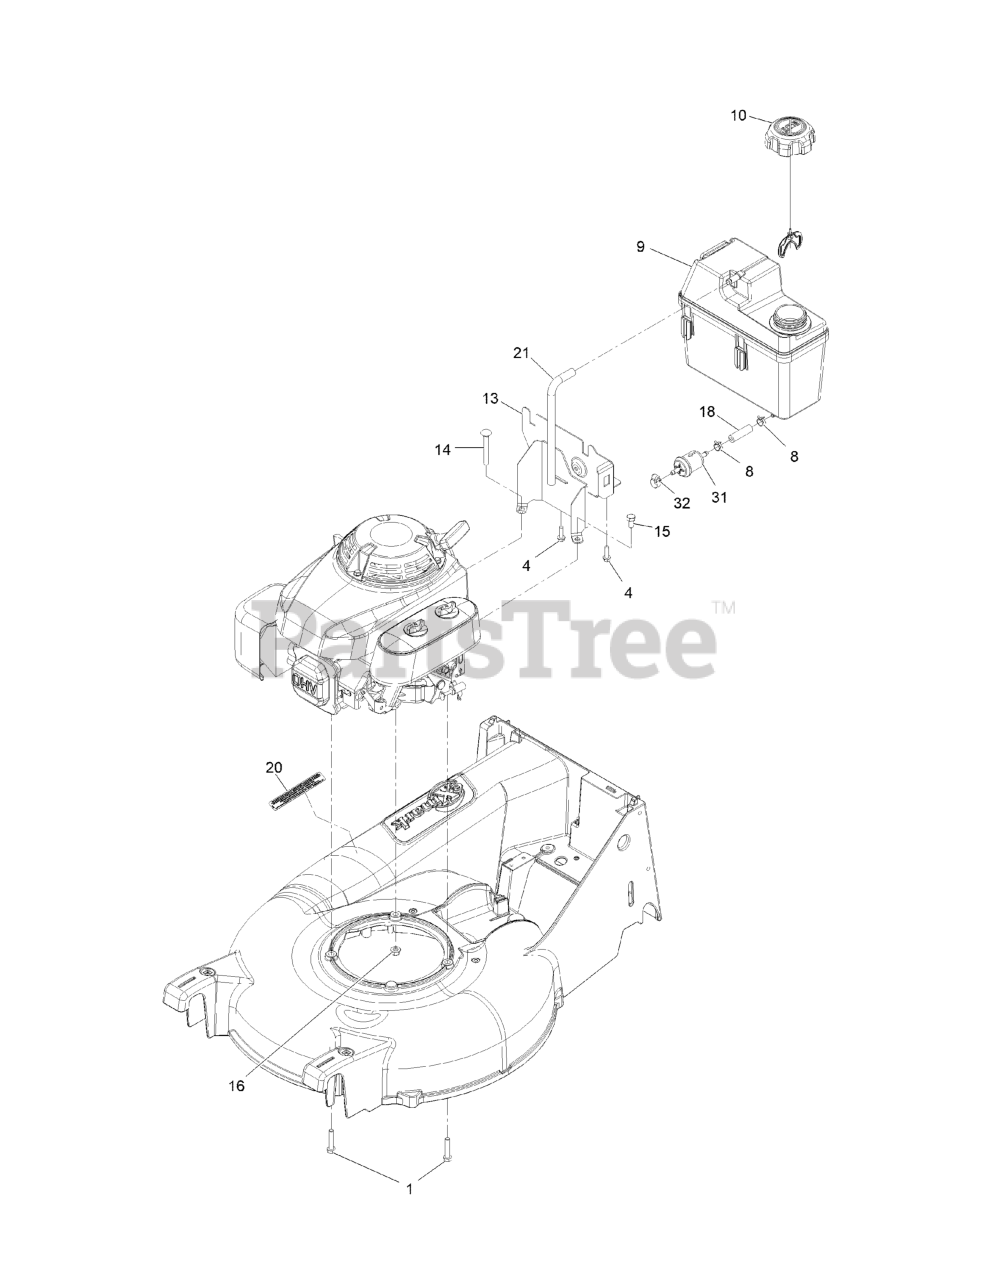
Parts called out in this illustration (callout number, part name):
1	SCREW-HH
4	SCREW-HWH
8	CLAMP-HOSE
9	TANK-FUEL
10	CAP-FUEL
13	BRACKET ASM
14	SCREW-CARR
15	SCREW-HH
16	NUT-HF, NI
18	HOSE-FUEL
20	DECAL-ARRESTOR, SPARK
21	HOSE-VENT, CANISTER
31	FILTER-FUEL
32	CLAMP-WORM
